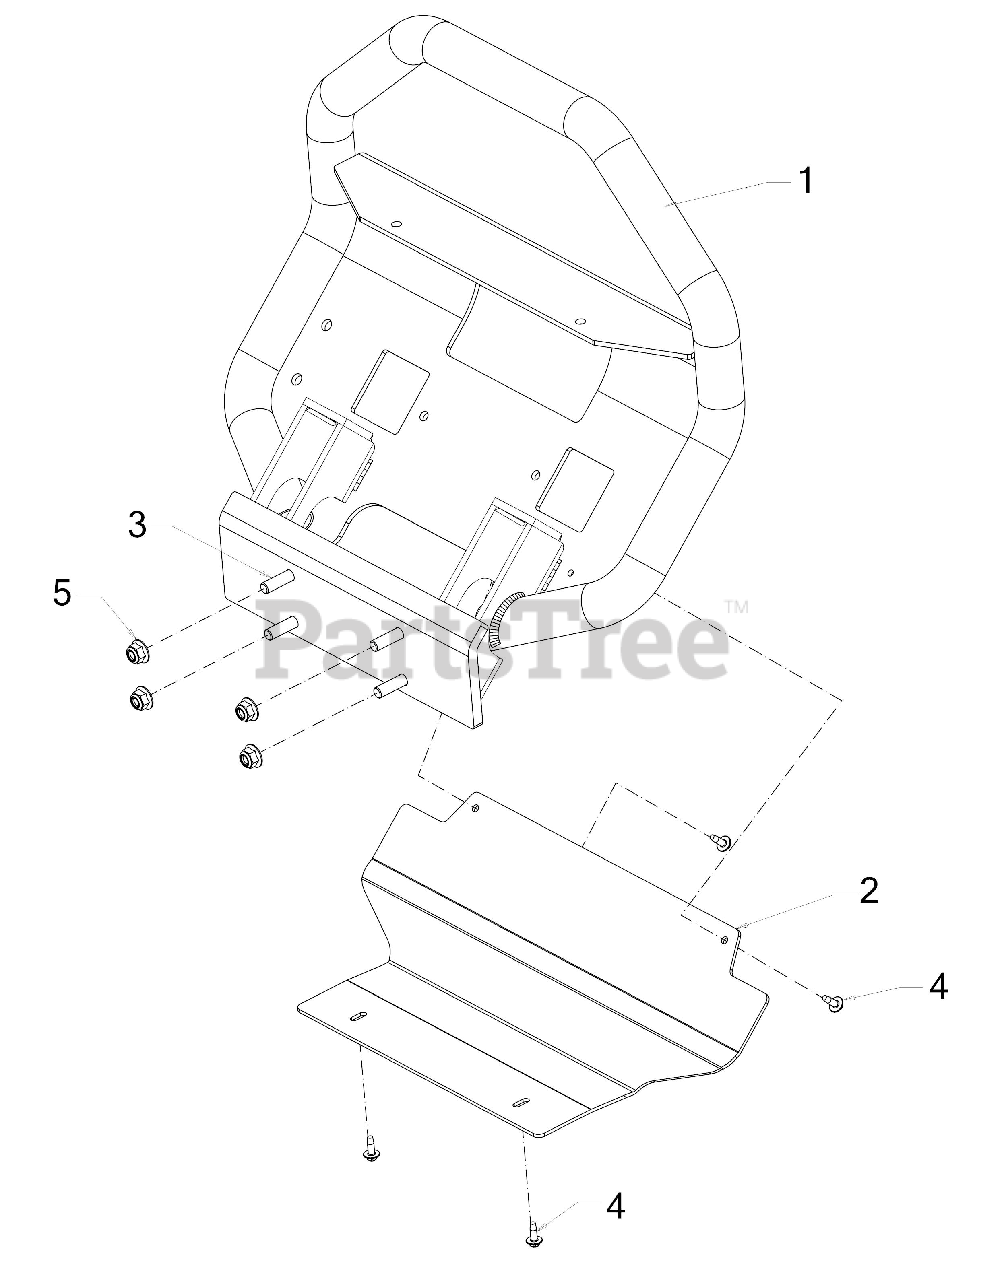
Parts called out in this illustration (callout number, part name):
1	BUMPER ASSEMBLY
2	SKID PLATE COVER
3	SCREW 3/8-16 x 1.50
4	SCREW 1/4-20 x .500
5	FLANGE LOCK NUT
